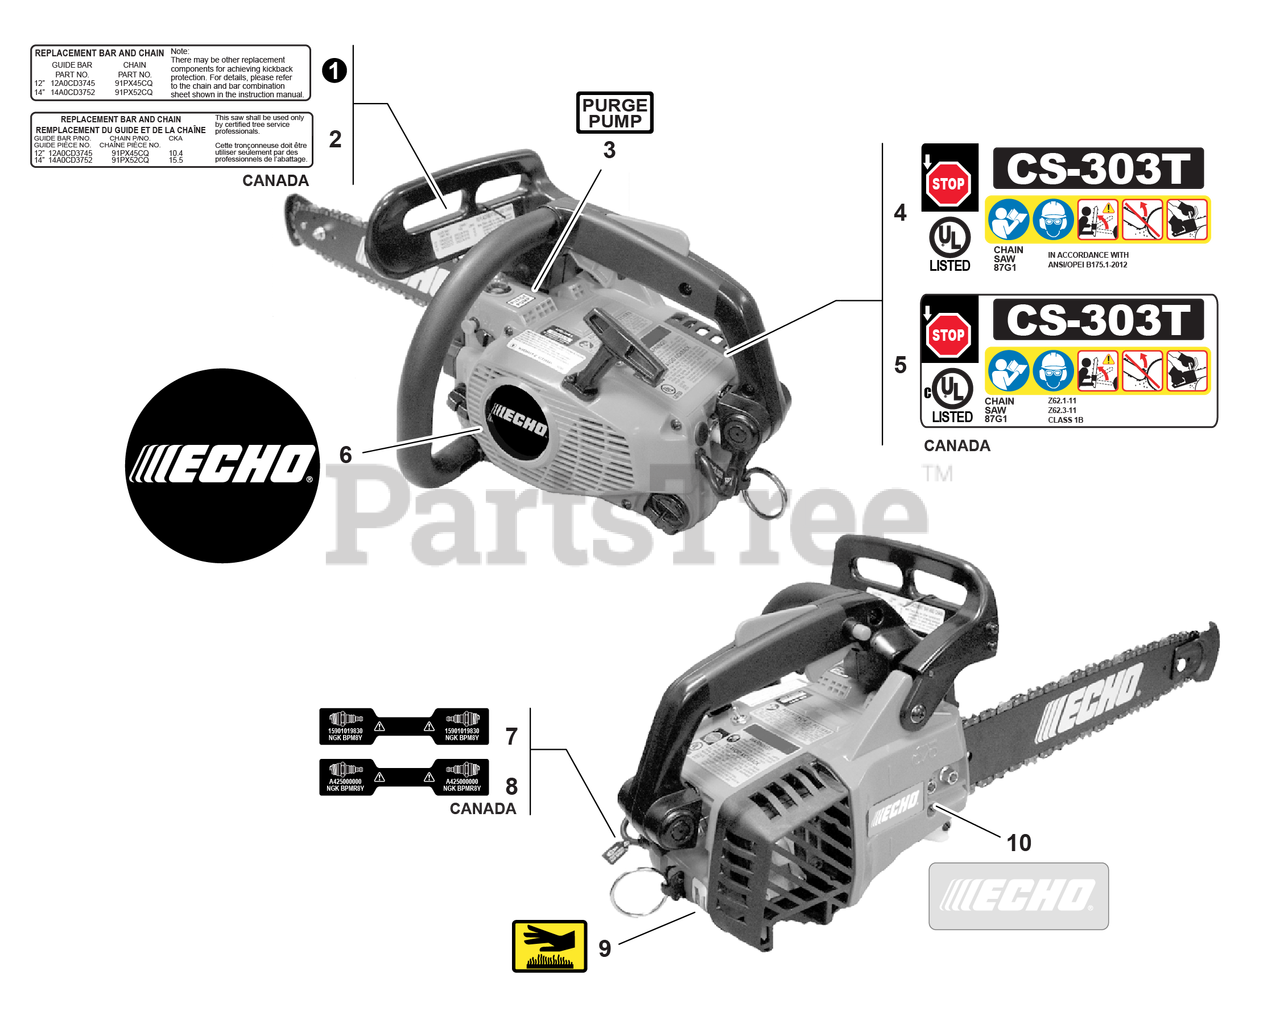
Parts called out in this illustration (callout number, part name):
1	LABEL, BAR & CHAIN
2	LABEL, BAR & CHAIN
3	LABEL, PURGE PUMP
4	LABEL, CAUTION
5	LABEL, CAUTION
6	LABEL, ECHO
7	LABEL, SPARK PLUG - BPM8Y
8	LABEL, SPARK PLUG - BPMR8Y
9	LABEL, CAUTION - HOT
10	LABEL, ECHO
